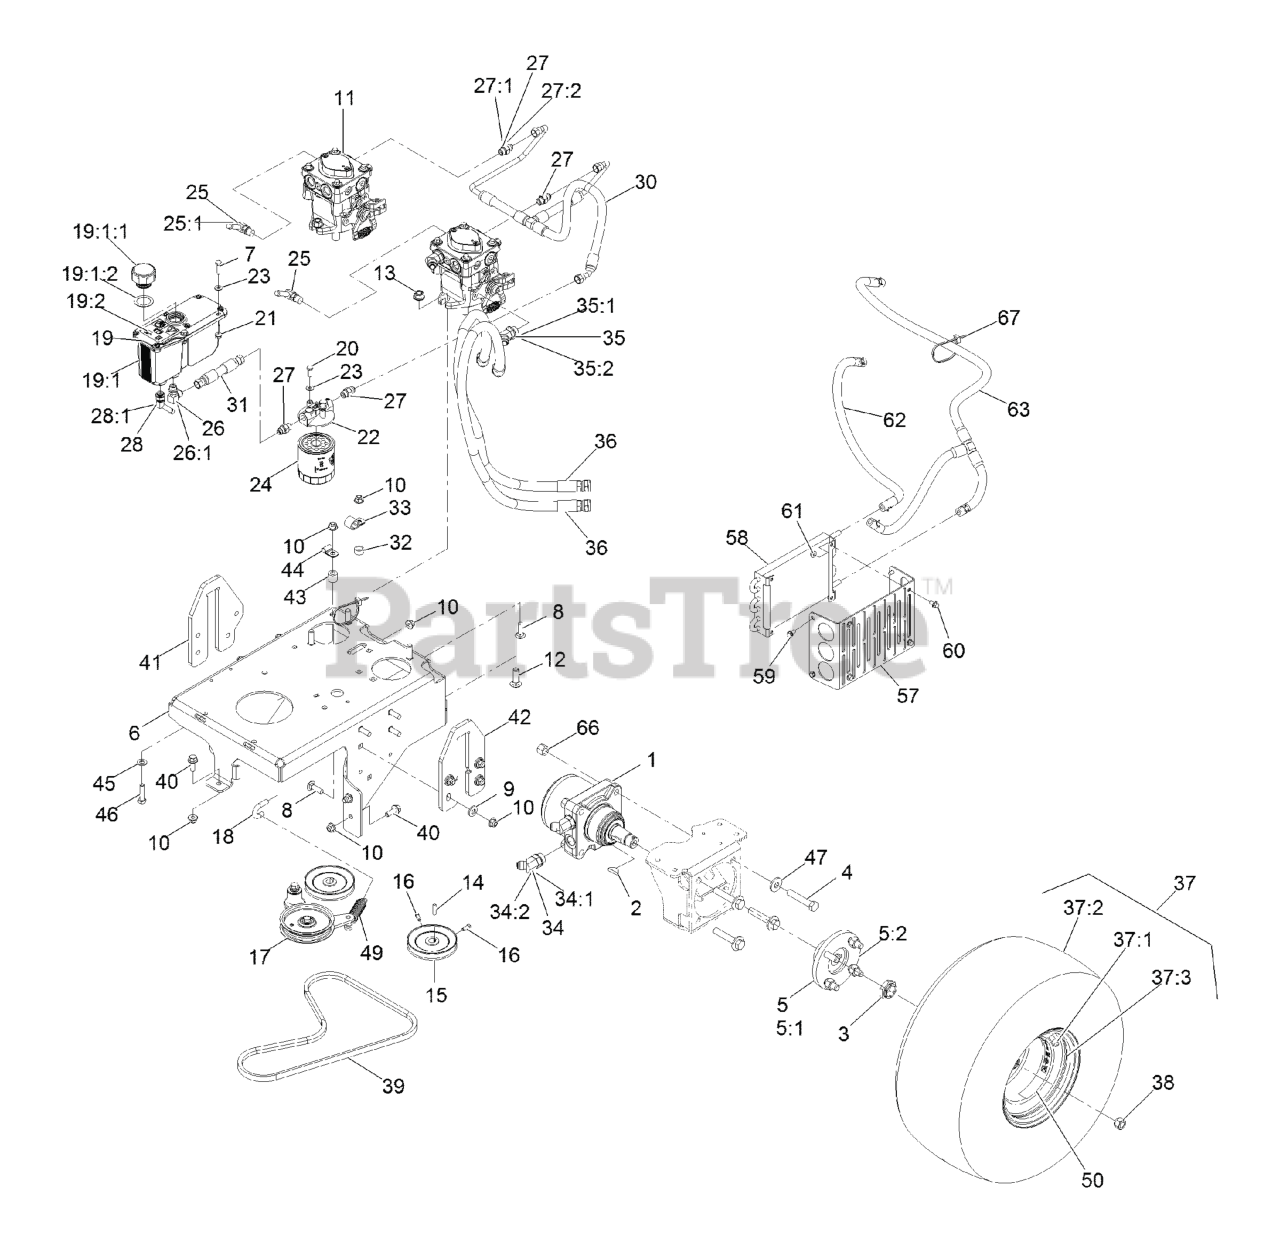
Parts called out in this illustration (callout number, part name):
1	MOTOR-WHEEL
2	KEY-WOODRUFF
3	LOCKNUT
4	SCREW-HH
5	WHEEL HUB / STUD ASM
5:1	HUB-WHEEL
5:2	STUD-TYPE, DRIVE
6	BASE, ENGINE
7	SCREW-HH
8	BOLT-CARR
9	WASHER-BELLEVILLE
10	NUT-HF, NI
11	PUMP - HYDRAULIC
12	BOLT-CARR
13	NUT-HF, NI
15	PULLEY-PUMP
16	SCREW-SET
17	PUMP IDLER ASM
18	ANCHOR, SPRING
19	RESERVOIR ASM
19:1:1	Cap-Reservoir, HYD
19:1:2	GASKET-CAP
19:2	DECAL-WARNING
20	SCREW-HH
21	NUT-HHF
22	HEAD-FILTER
23	WASHER-FLAT
24	FILTER-25 MICRON, BI-DIRE
25	FITTING-ELBOW, 90
25:1	O-RING
26	FITTING-ELBOW, 90 DEG
27	FITTING-STRAIGHT
28	FITTING-BARBED, 45 DEG
28:1	O-RING
30	HOSE ASSEMBLY - CHARGE
31	HYD HOSE ASM
32	SPACER-WHEEL
33	CLIP-LOOM
34	FITTING-HYD, 45 DEG
35	FITTING-HYD, 45 DEG
36	HYD HOSE ASM
37	WHEEL/TIRE ASM
37:1	RIM-8 INCH
37:3	Stem-Valve
38	NUT-LUG
39	BELT-V, LOWER PTO
40	SCREW-HHF 3/8-16 X 1
41	PLATE-LIFT, RH
42	PLATE, LIFT LH
44	CLIP-TUBE
45	WASHER-FLAT
46	SCREW-HH
47	WASHER-SPRING
49	SPRING-EXTENSION
50	DECAL-TORQUE, WHEEL HUB LUG
57	BRACKET, COOLER MOUNTING
59	SCREW-HWH
60	SCREW-HHF
61	NUT-KEPS
62	HOSE-HYDRAULIC
63	HOSE ASM-HYD LP 3/8
66	NUT-LOCK, NI
